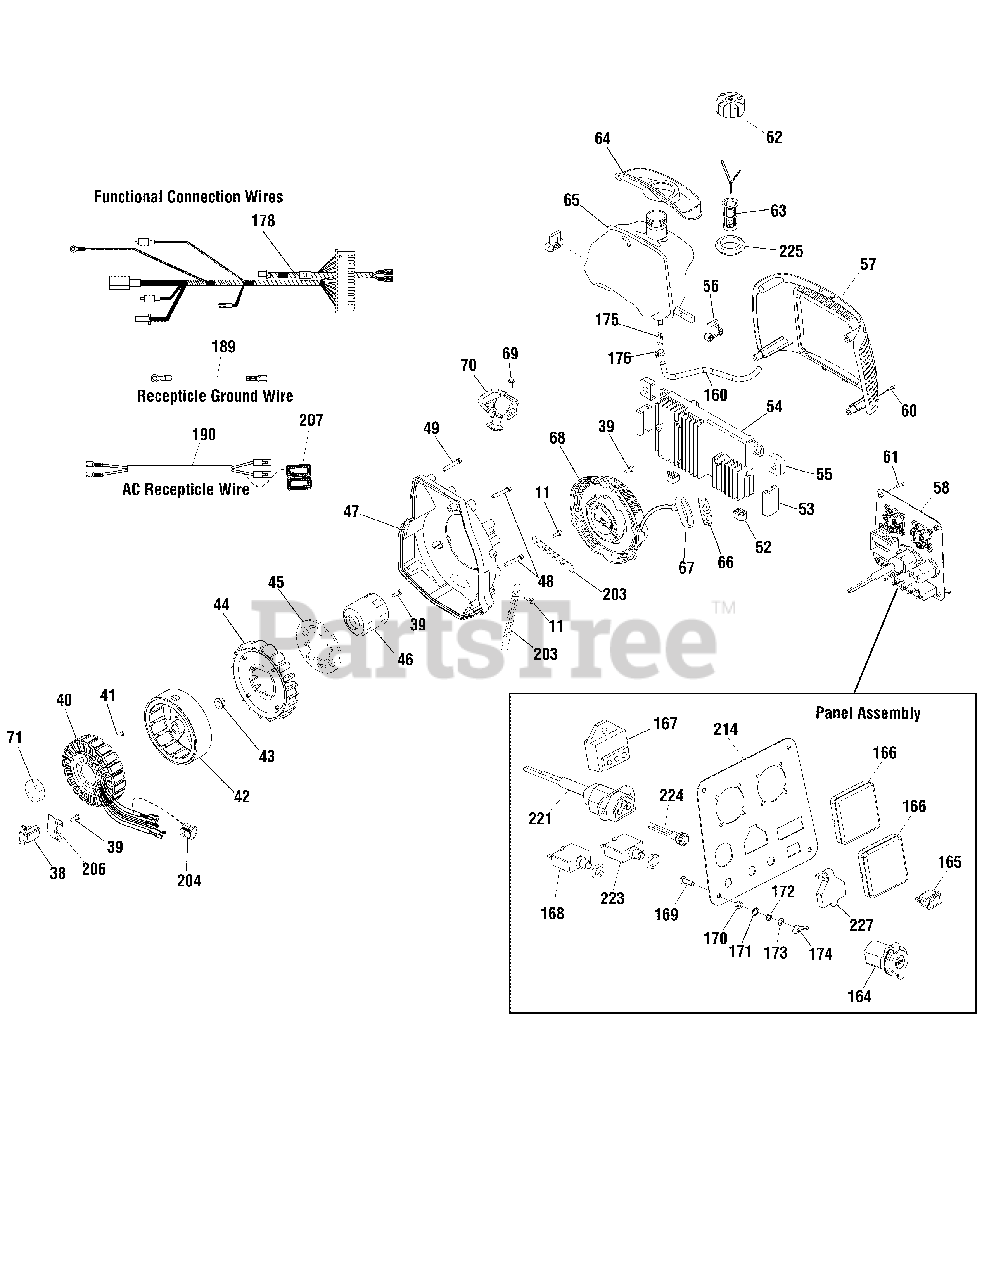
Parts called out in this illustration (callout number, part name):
11	BOLT
38	TRIGGER-IGNITION
45	TERMINAL
47	COVER-FAN
48	BOLT
49	BOLT
52	MOUNT-VIBRATION
53	MOUNT-VIBRATION
55	MOUNT-VIBRATION
56	MOUNT-VIBRATION
58	PANEL-CONTROL ASSY
60	SCREW
61	SCREW
63	FILTER-FILLER NECK
64	PAD-FUEL TANK
67	GRIP
68	STARTER-REWIND
69	SCREW
71	SEAL-OIL
167	LIGHT-INDICATOR
168	CIRCUIT BREAKER
175	FILTER-FUEL TANK
176	CLAMP
203	BRACKET
204	COVER-RUBBER
206	PROTECTOR BOARD
214	PANEL-CONTROL
223	CIRCUIT BREAKER, 15A
